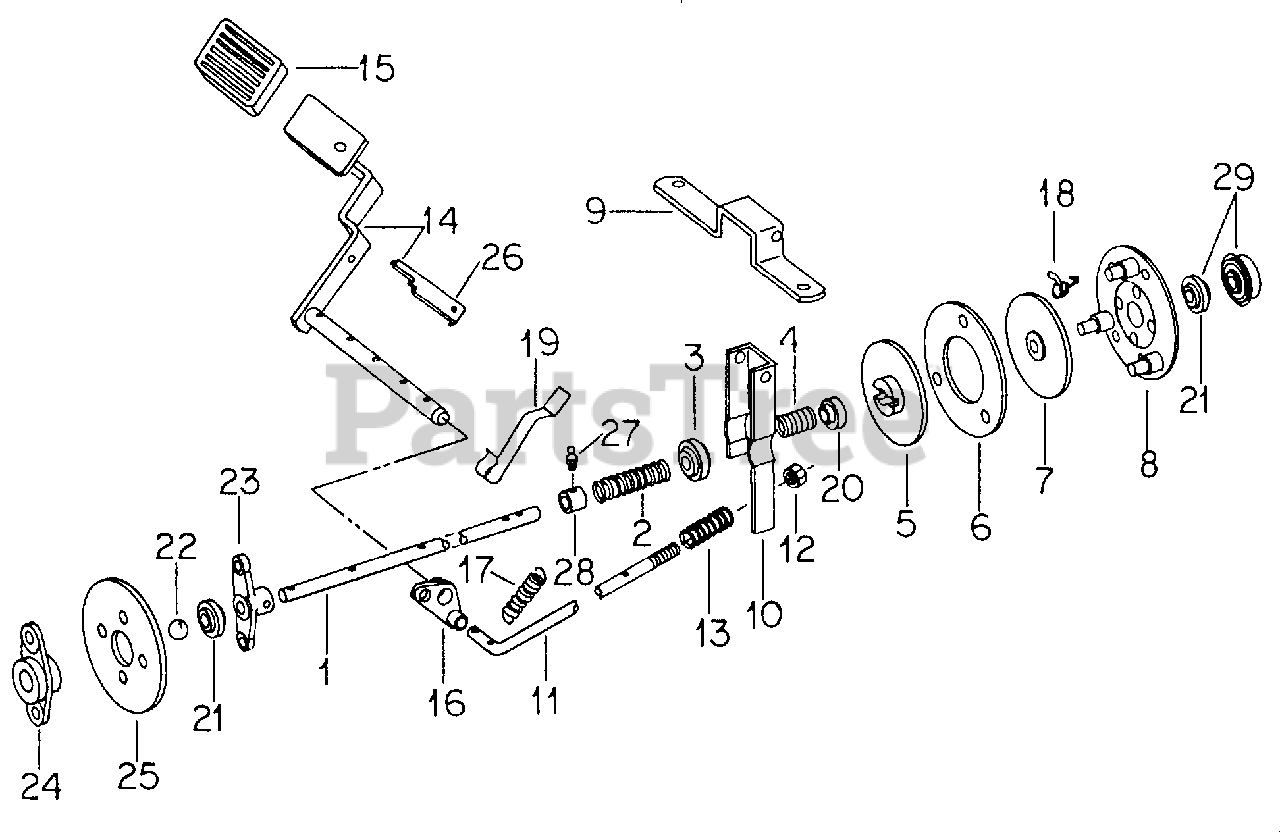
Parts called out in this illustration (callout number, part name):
1	Shaft w/Tag, Clutch Drive
2	Spring, Loading
3	Bearing, Throwout Ball
4	Spring, Teasing
5	Hub Assy, Pressure Plate
6	Disc, Clutch Friction
7	Hub Assy, Pressure Plate Locating
8	Plate Assy, Driving
9	Hanger Assy, Clutch Lever
10	Lever, Release
11	Rod, Clutch Release
12	Nut, 3/8-24 Cdp Hex Nylon Insert
13	Spring, Clutch Release Rod
14	Pedal Assy, Clutch
15	Pad, Pedal
16	Arm, Clutch & Brake Pedal
17	Spring, Pedal Return
18	Spring, Clutch Driving Disc
19	Spring, Safety Switch
20	Spacer, Spring
21	Bushing, Ball
22	Ball, 5/8 Cr Stl
23	Arm, Coupling
24	Coupling, Drive Shaft
25	Disc, Flex Coupling
27	Fitting, 1/4-28 Taper Drive Tread Lube
28	Bushing, Lubricating
29	Hub Assy, Pilot
